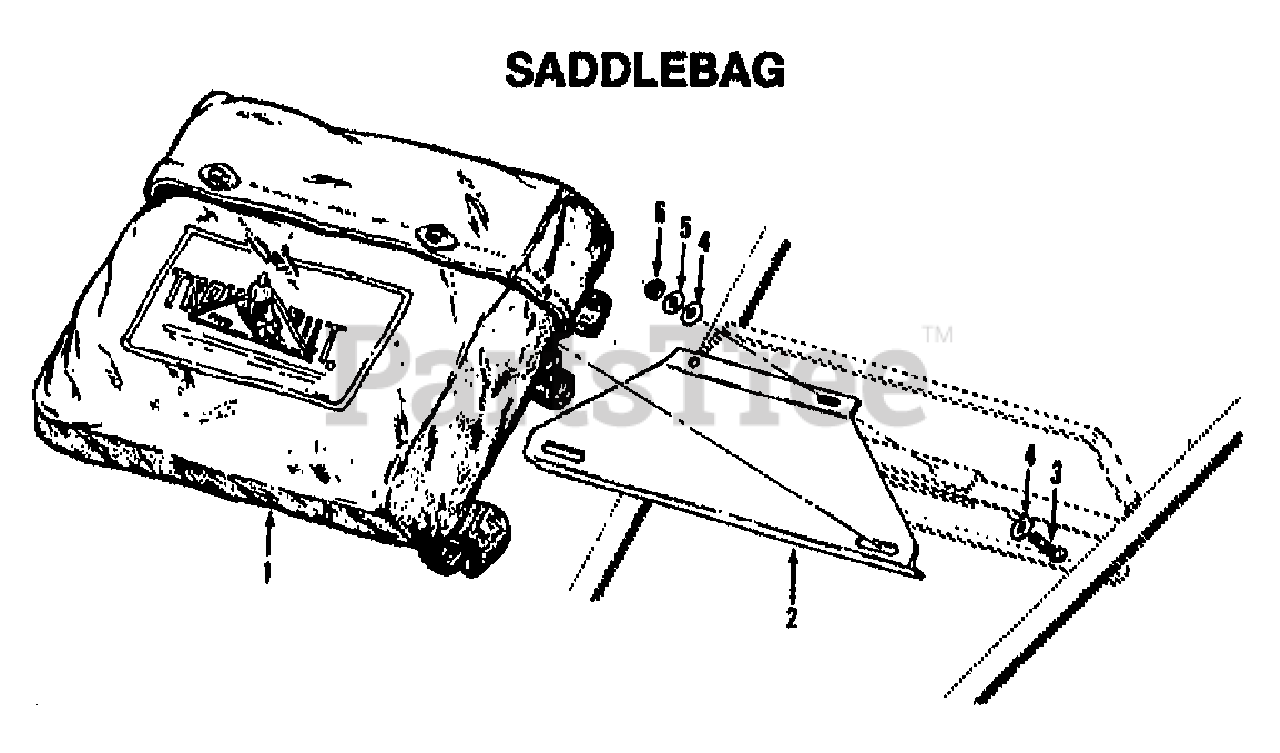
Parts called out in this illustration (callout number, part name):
1	SADDLEBAG - REINFORCED VINYL W/CLOTH BACKING
2	PLATE-SADDLEBAG MTG
3	SCR-PH HD M10-24X1.375
4	WASHER-#10
5	WASHER-LK M10
6	NUT-HEX M10-24
